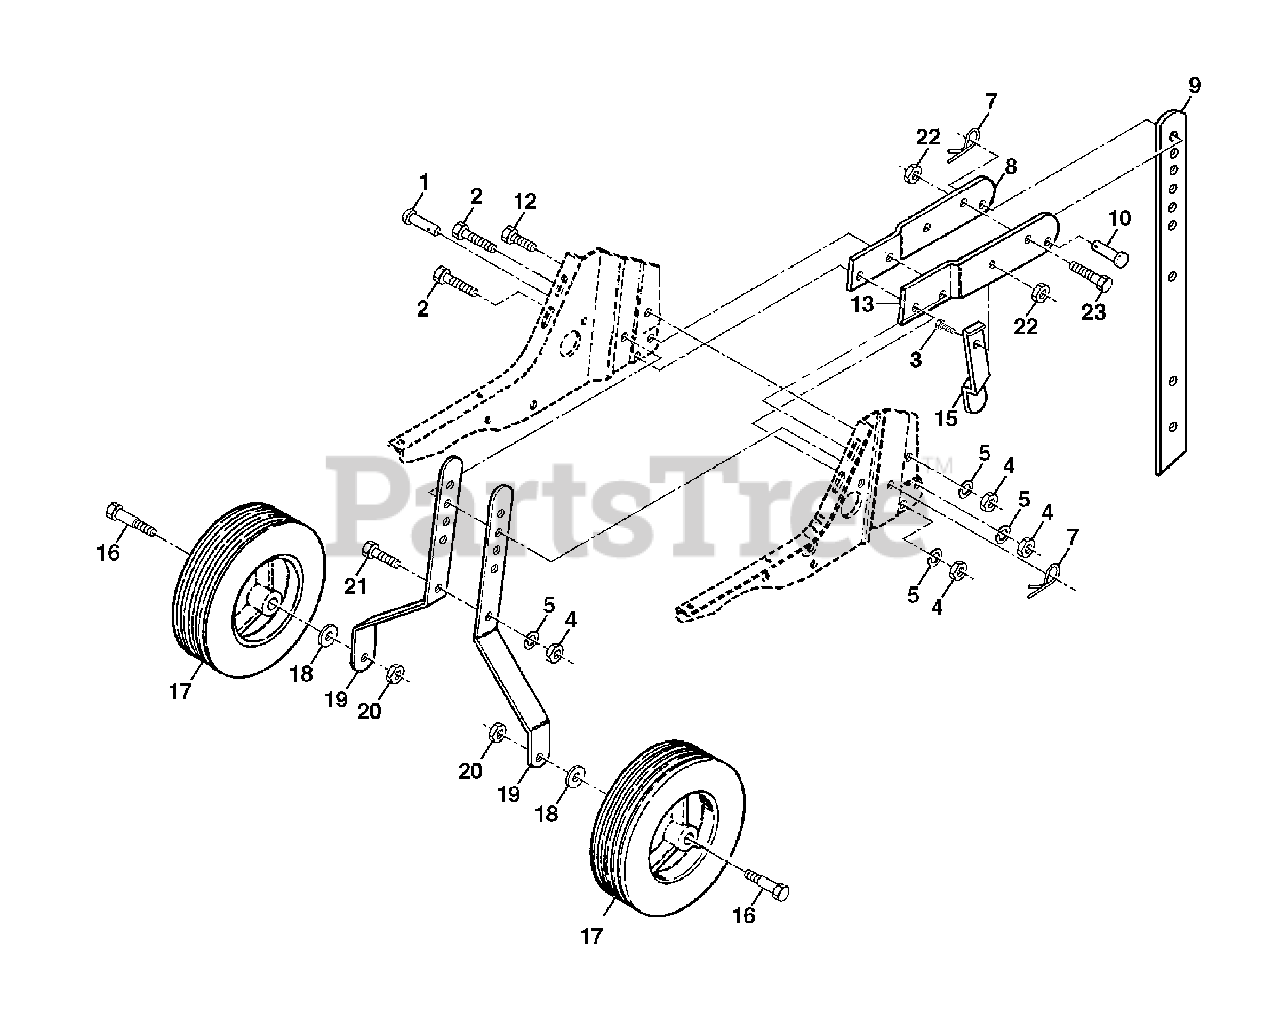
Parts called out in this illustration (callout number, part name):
1	Pin, Clevis
2	Bolt, Hex 5/16-18 x 1-1/4
3	Bolt, Hex 5/16-18 x 3/4
4	Nut, Hex 5/16-18
5	Washer, Lock 5/16
7	Clip, Hairpin
8	Support, Depth Stake, R.H.
9	Stake, Depth
10	Pin, Clevis
12	Bolt, Hex 5/16-18 x 3/4
13	Support, Depth Stake, L.H.
15	Spring, Stake
16	Bolt, Shoulder
18	Washer 13/32 x 13/16 x 11 Ga.
19	Bracket, Wheel
20	Locknut, Crown 3/8-16
21	Bolt, Hex 5/16-18 x 1
22	Locknut, w/insert 5/16-18
23	Bolt, Fin Hex 5/16-18 UNC x 1-1/2
